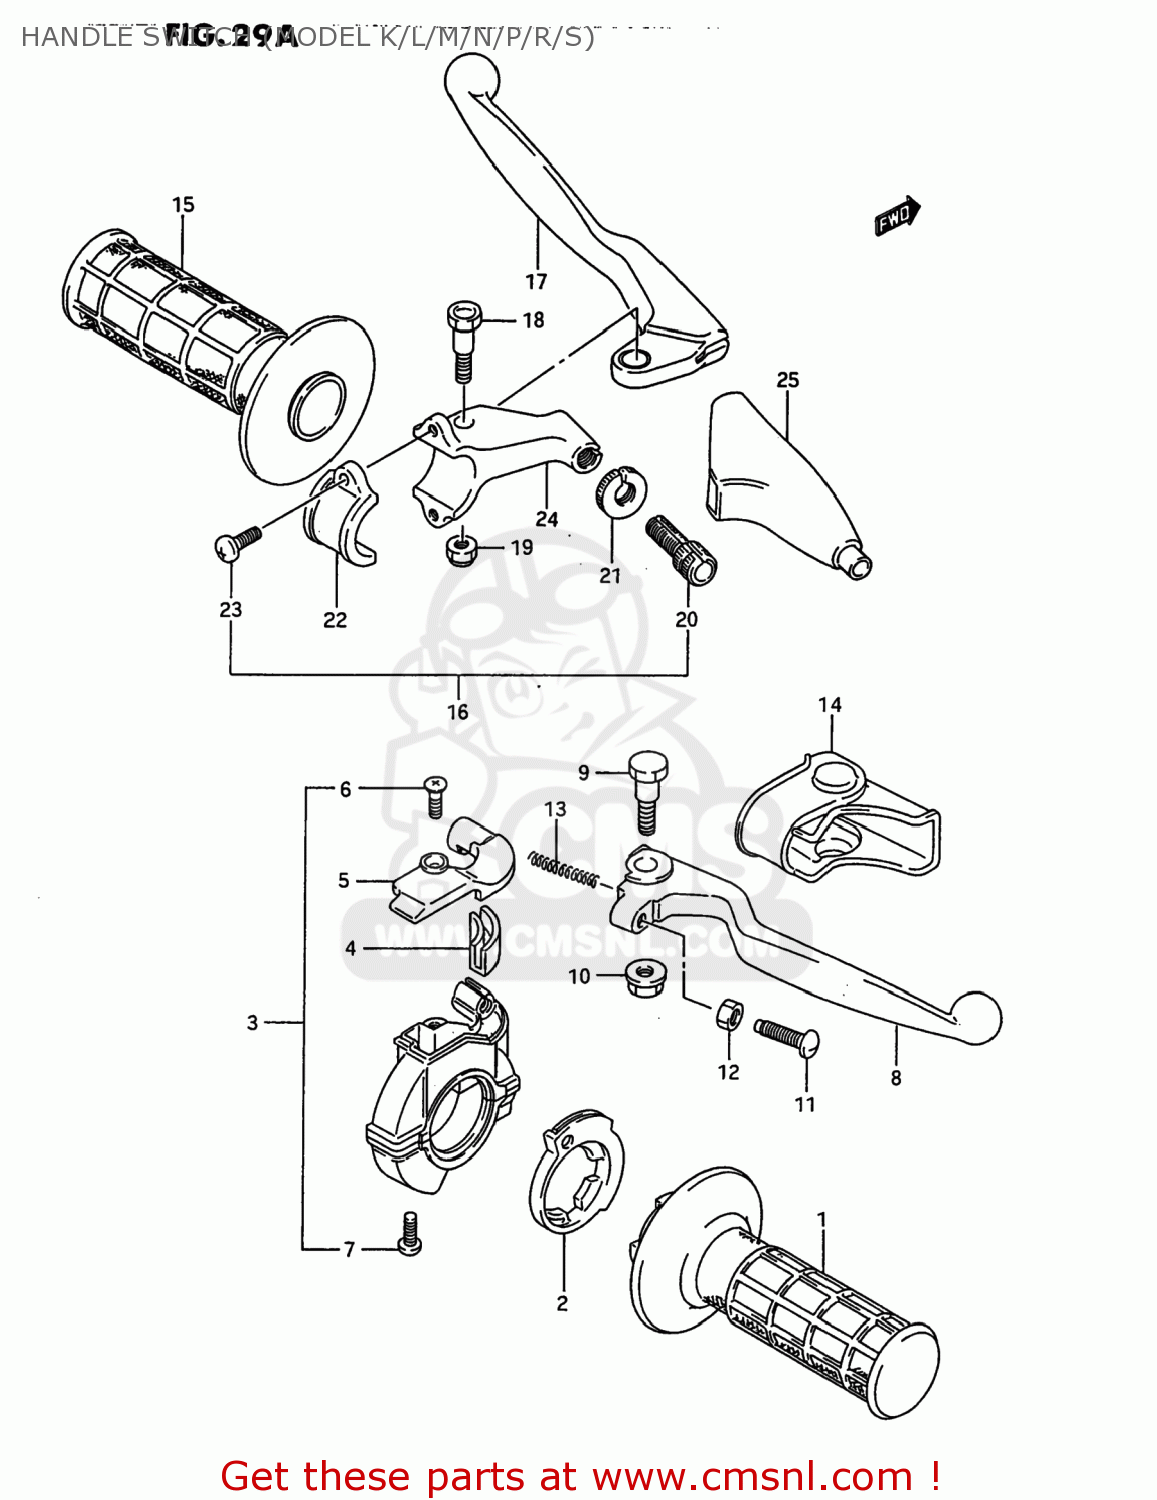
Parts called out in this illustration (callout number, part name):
1	GRIP,THROTTLE
2	ROTOR,THROTTLE GRIP
3	CASE ASSY,THROTTLE
4	GUIDE PIECE,THROTTLE
5	COVER,THROTTLE CASE
6	SCREW,UPPER
7	SCREW
8	LEVER,BRAKE
9	BOLT,BRAKE LEVER
10	NUT,BRAKE LEVER
11	BOLT,ADJUST
12	NUT ,5MM
13	SPRING,RETURN
14	COVER,BRAKE LEVER
15	GRIP,L
16	LEVER ASSY,CLUTCH
17	LEVER,CLUTCH
18	BOLT,LEVER
19	NUT 6MM
20	ADJUSTER,CABLE
21	NUT,CABLE ADJUSTER
22	BRACKET,CLUTCH LEVER HOLDER
23	SCREW(5X14)
24	HOLDER,CLUTCH LEVER
25	COVER,CLUTCH LEVER
